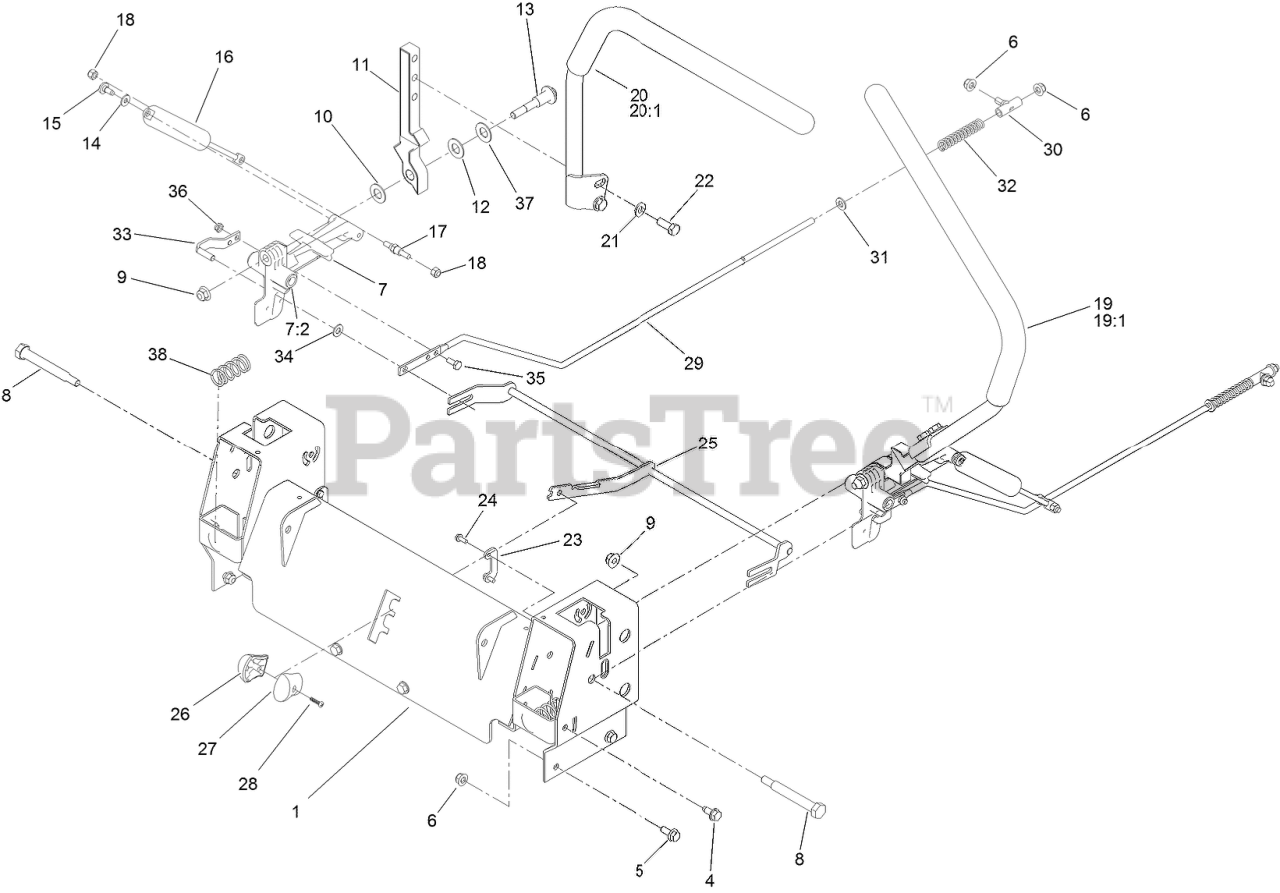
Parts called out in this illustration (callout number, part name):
1	CONTROL BOX ASM
4	SCREW-HWHTF
5	SCREW-HHF
6	NUT-HF, NI
7	ACTUATOR ARM ASM
7:2	BUSHING-FLANGE
8	BOLT-PIVOT
9	NUT-HF, NI
10	WASHER-NYLON
11	ARM-CONTROL
12	WASHER
13	BOLT-PIVOT
14	WASHER
15	SCREW-SHOULDER
16	DAMPER
17	STUD-DAMPER
18	NUT-LOCK, NI
19	HANDLE-CONTROL, LH
20	HANDLE-CONTROL, RH
21	WASHER-FLAT
22	SCREW-HH
23	RETAINER
24	SCREW-TAPTITE
25	SPEED CONTROL ASM
26	KNOB-RH
27	KNOB-LH
28	SCREW-PPH
29	ROD-HYDRO
30	MOUNT-ROD, HYDRO
31	WASHER-PLAIN
32	SPRING-RETURN, NEUTRAL
33	PIN-ROD, HYDRO
34	SPACER-NYLON
35	SCREW-HH
36	NUT-LOCK, NI
37	WASHER-BELLEVILLE
38	SPRING-RETURN
